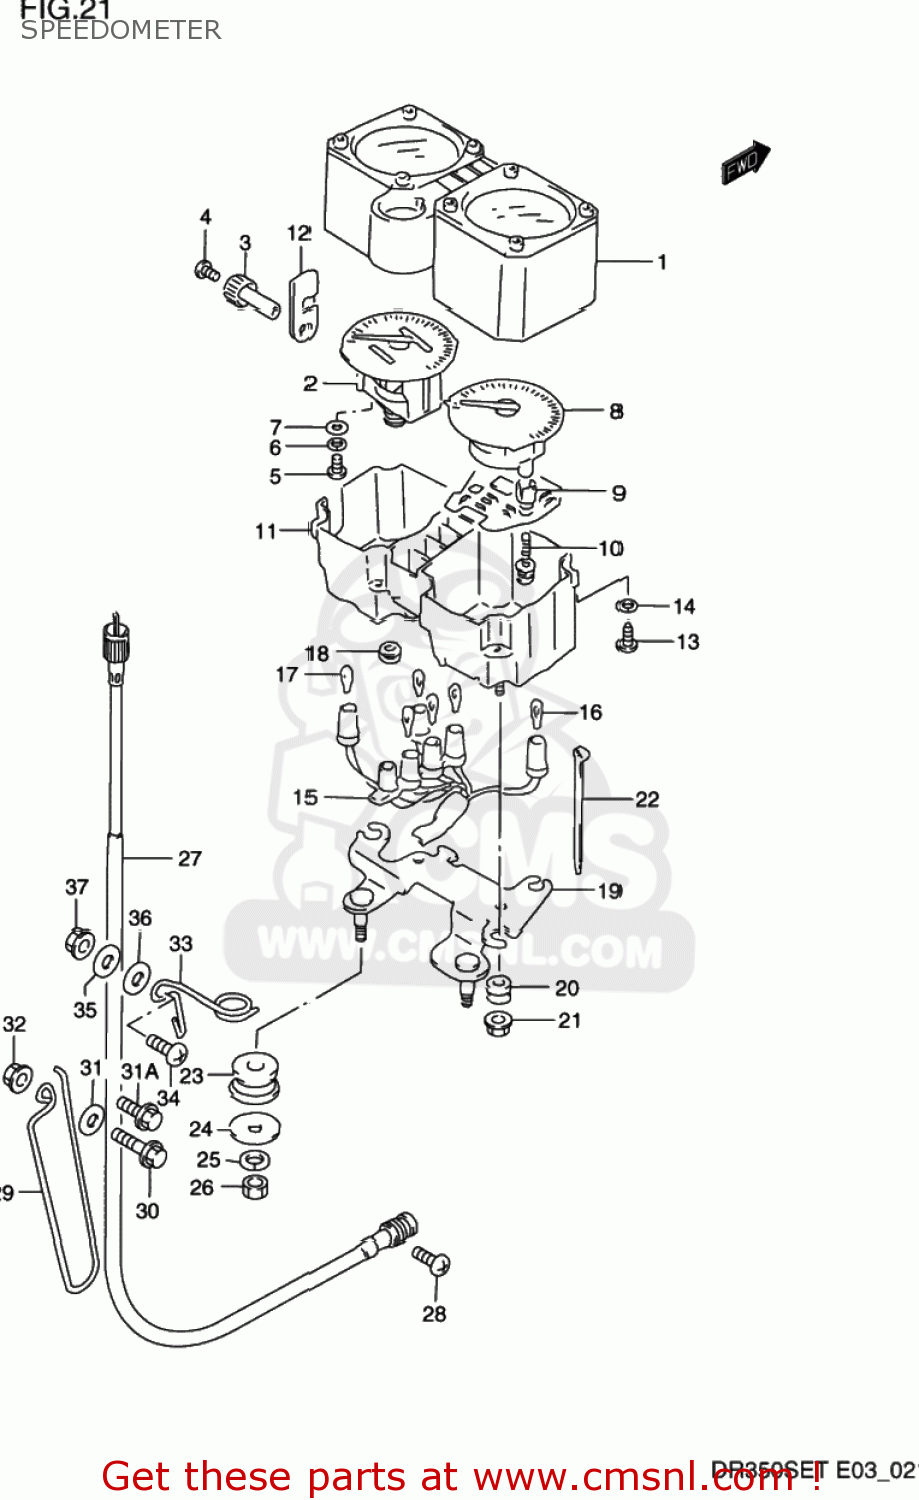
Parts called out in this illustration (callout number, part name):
1	HOOD,METER
2	SPEEDOMETER(MILE/KILO)
3	KNOB,TRIP
4	SCREW,TRIP KNOB
5	SCREW
6	WASHER,LOCK
7	WASHER
8	TACHOMETER
9	SPACER
10	SCREW
11	CASE,METER
12	CUSHION,METER
13	SCREW
14	WASHER,LOCK
15	SOCKET,METER
16	BULB(12V3W,WB371,T7)
17	BULB(12V1.7W,WB372,T7)
18	CAP
19	BRACKET
20	CUSHION,METER
21	NUT
22	CLAMP
23	CUSHION,METER BRACKET
24	WASHER (8.5X20X1.6)
25	WASHER,LOCK
26	NUT
27	CABLE ASSEMBLY,SPEEDOMETER
28	SCREW
29	GUIDE,METER CABLE NO.2
30	BOLT
31	WASHER
31A	BOLT(6X20)
32	NUT
33	GUIDE,METER CABLE NO.3
34	SCREW
35	WASHER
36	WASHER
37	NUT
